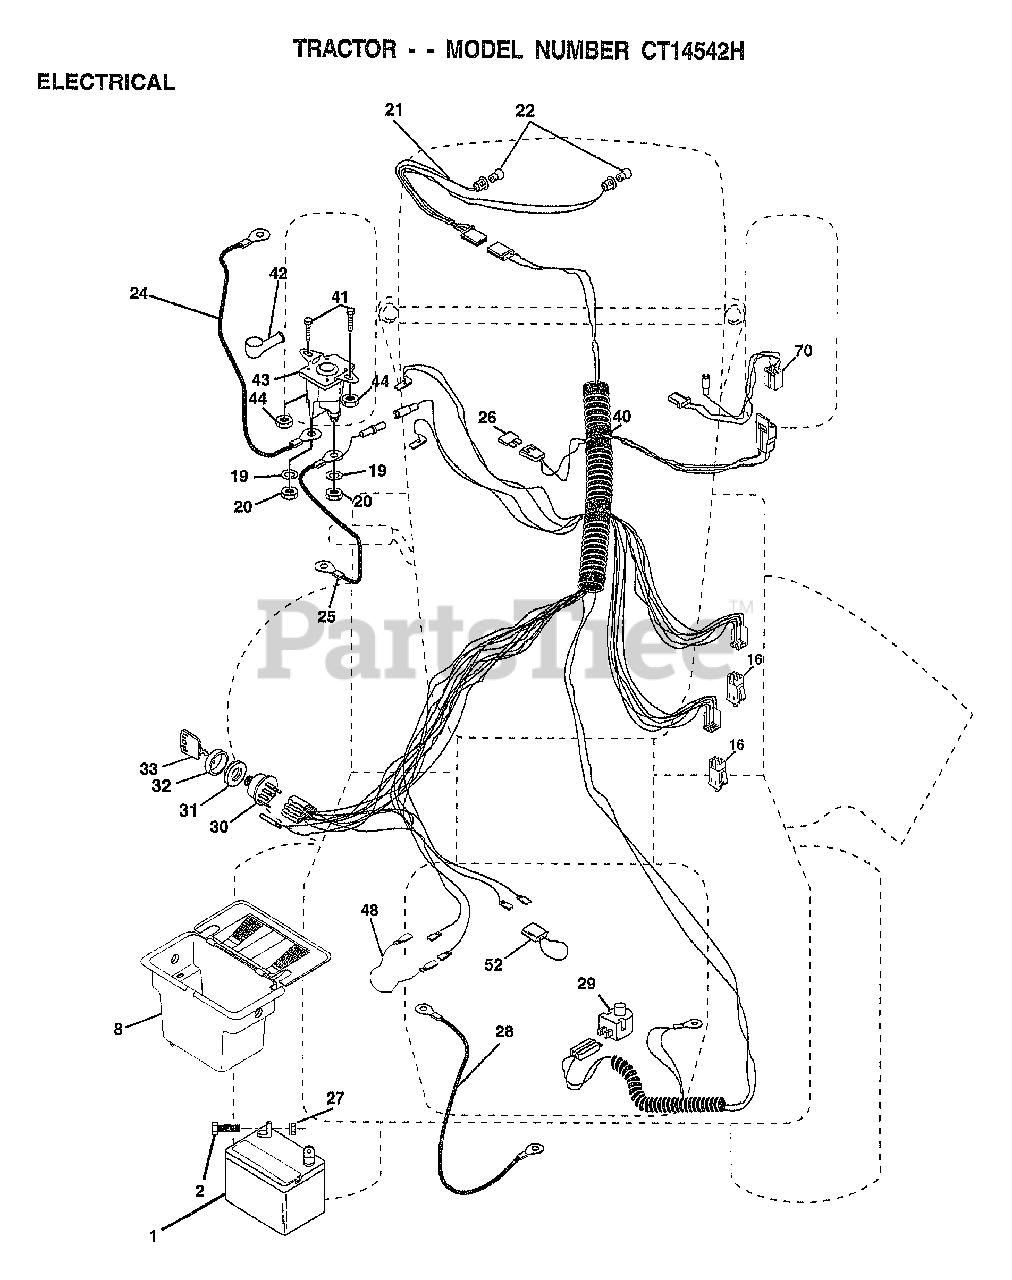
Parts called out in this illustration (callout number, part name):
2	BOLT LT
8	"CASE,BATTERY.MECH"
16	SWITCH INTERLOCK
20	NUT
21	HARNESS.ASM.LIGHT W/4152J
22	HEADLAMP BULB
24	"CABLE T, BATTERY"
25	CABLE.BTRY.6GA.RD
26	FUSE.15 AMP
27	NUT
28	CABLE T
29	SWITCH SEAT
30	SWITCH IGN 4POS
31	NUT IGNITION
32	COVER KEY SWITCH
33	KEY
40	HARNESS.IGNITION
41	BOLT HXHD FIN
44	NUT HXKEP 1/4X20
48	ADAPTER AMMETER
52	PROTECTION LOOP
70	HARNESS.ENGINE
